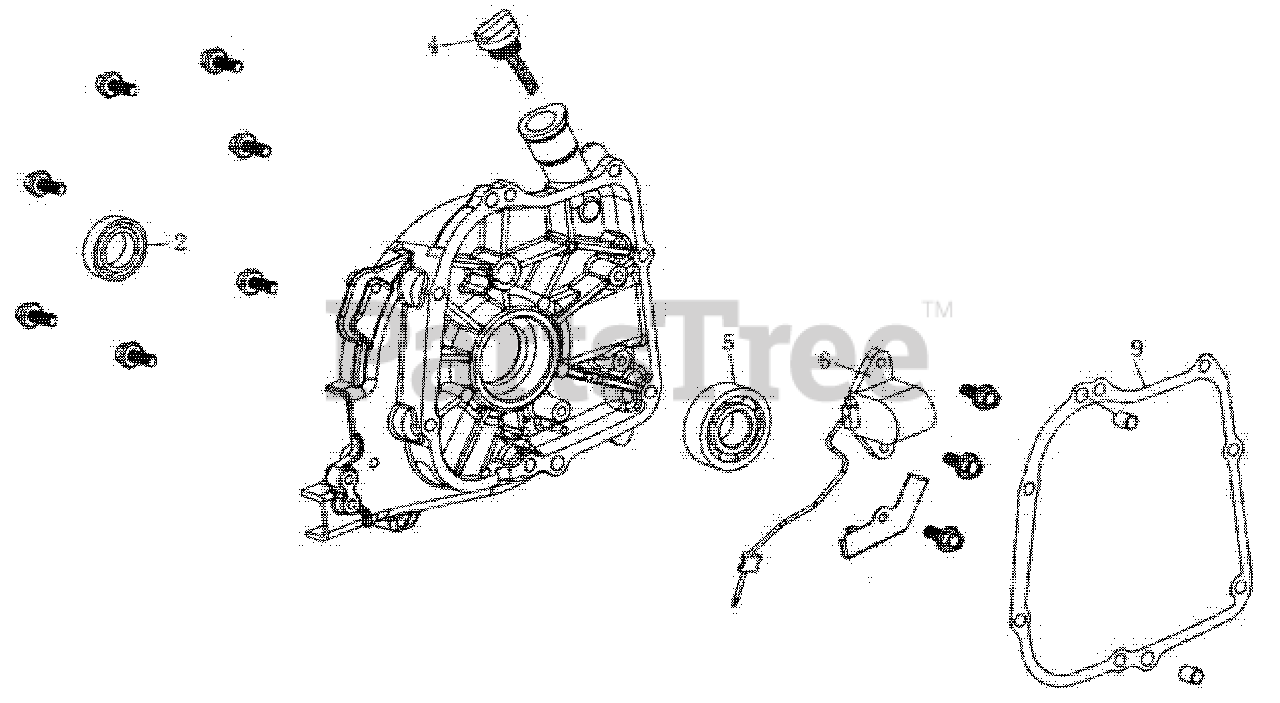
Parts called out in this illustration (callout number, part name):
2	OIL SEAL D=20_D=35_B=5
4	CAP ASSY
5	BALL BEARING 6204
6	OIL LEVEL SWITCH
9	PACKING , CASE COVER
